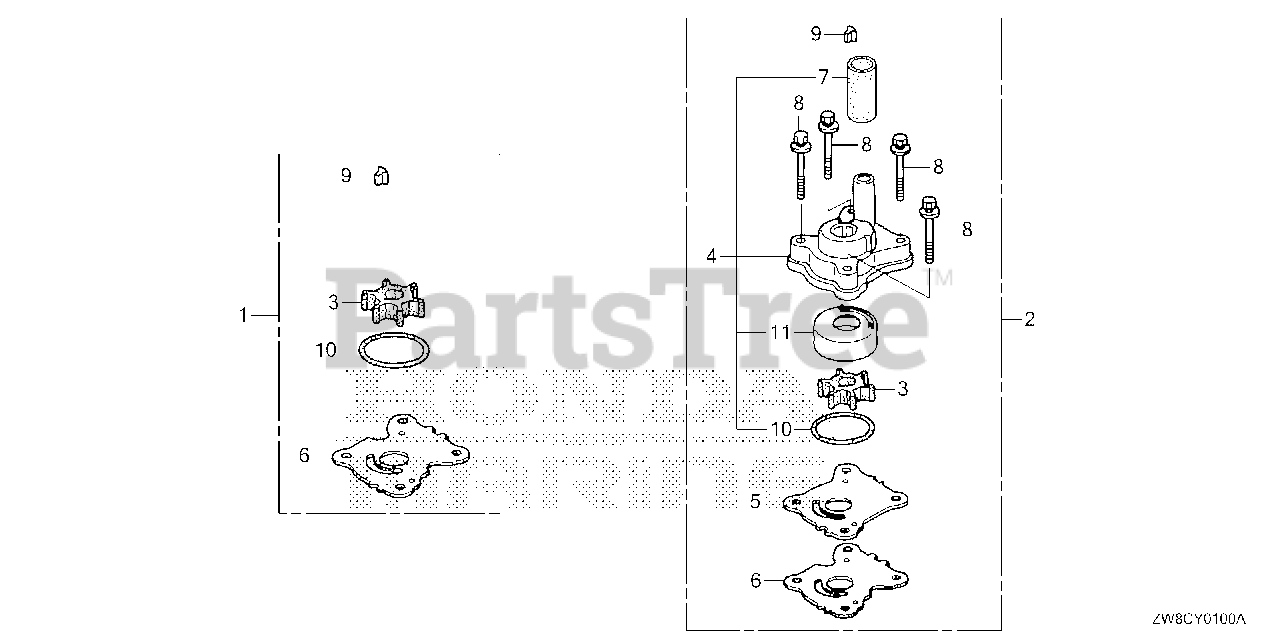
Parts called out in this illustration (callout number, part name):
1	PUMP KIT, IMPELLER
2	PUMP KIT, IMPELLER
3	IMPELLER, PUMP (S,L)
4	HOUSING ASSY., IMPELLER
5	COVER, IMPELLER
6	GASKET, IMPELLER
7	RING, WATER TUBE SEAL
8	BOLT-WASHER (6X50)
9	KEY, WOODRUFF
10	O-RING (42.2X2.4)
11	LINER, PUMP
